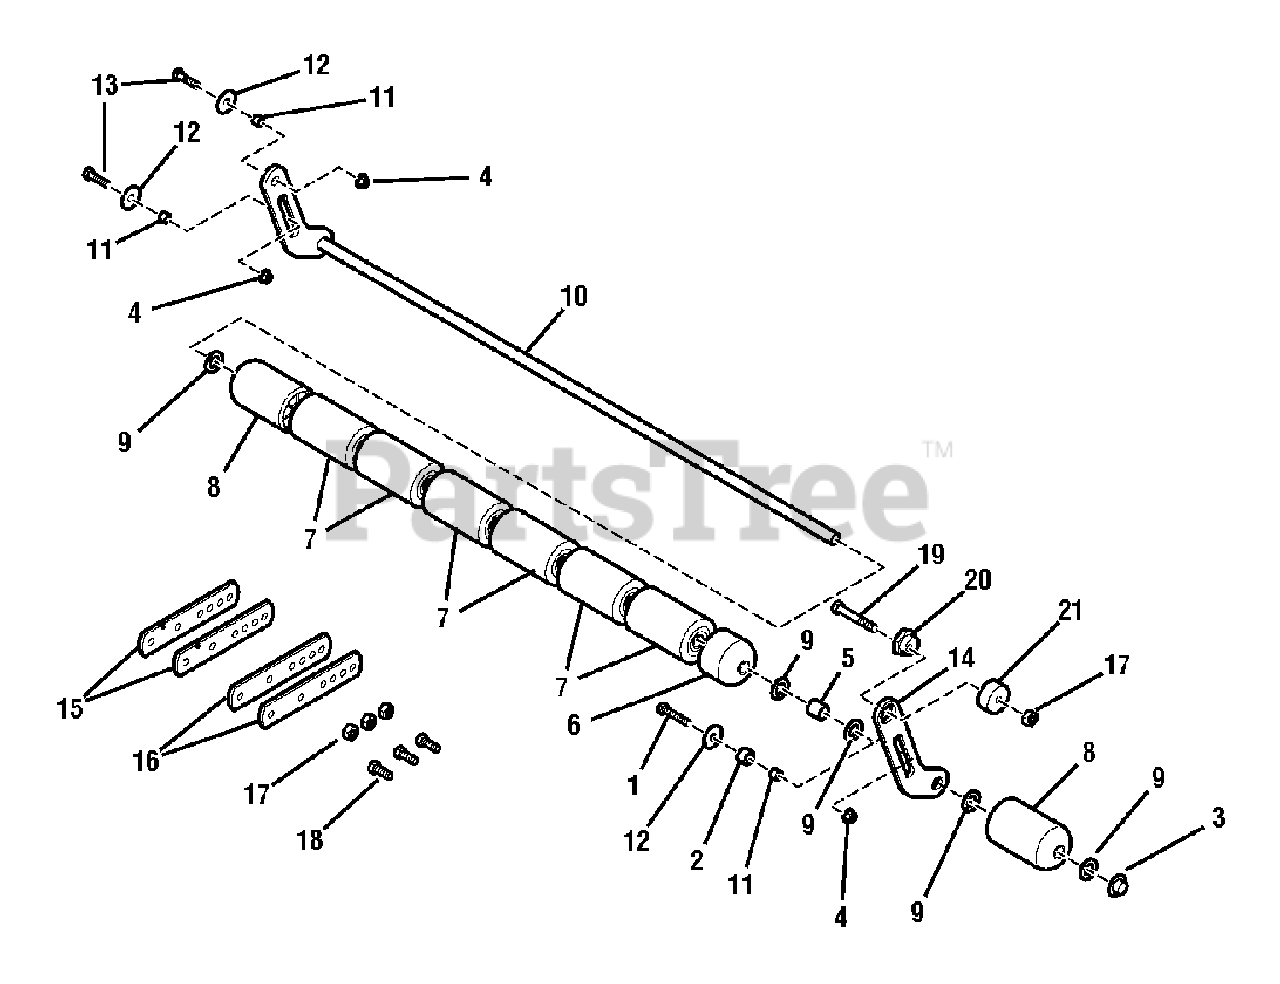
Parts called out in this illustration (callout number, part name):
1	Capscrew, 5/16-18 x 1-3/4
2	Spacer
3	Nut, push, 5/8, capped
4	Nut, lock, flanged, 5/16-18
5	Spacer
6	Roller, round end, 2.05 long
7	Roller, flat end, 4.1 long
8	Roller, round end, 4.1 long
9	Washer, flat, 5/8
10	Roller Shaft Assembly
11	Spacer
12	Washer, Flat 5/16
13	Capscrew, 5/16-18 x 1-1/4
14	Bar, roller
15	Bar, Extension (notched)
16	Bar, Extension
17	Nut, Lock, Flanged, 3/8-16
18	Capscrew, 3/8-16 x 1
19	Capscrew, 3/8-16 x 2
20	Adjusting Nut
21	Spacer
